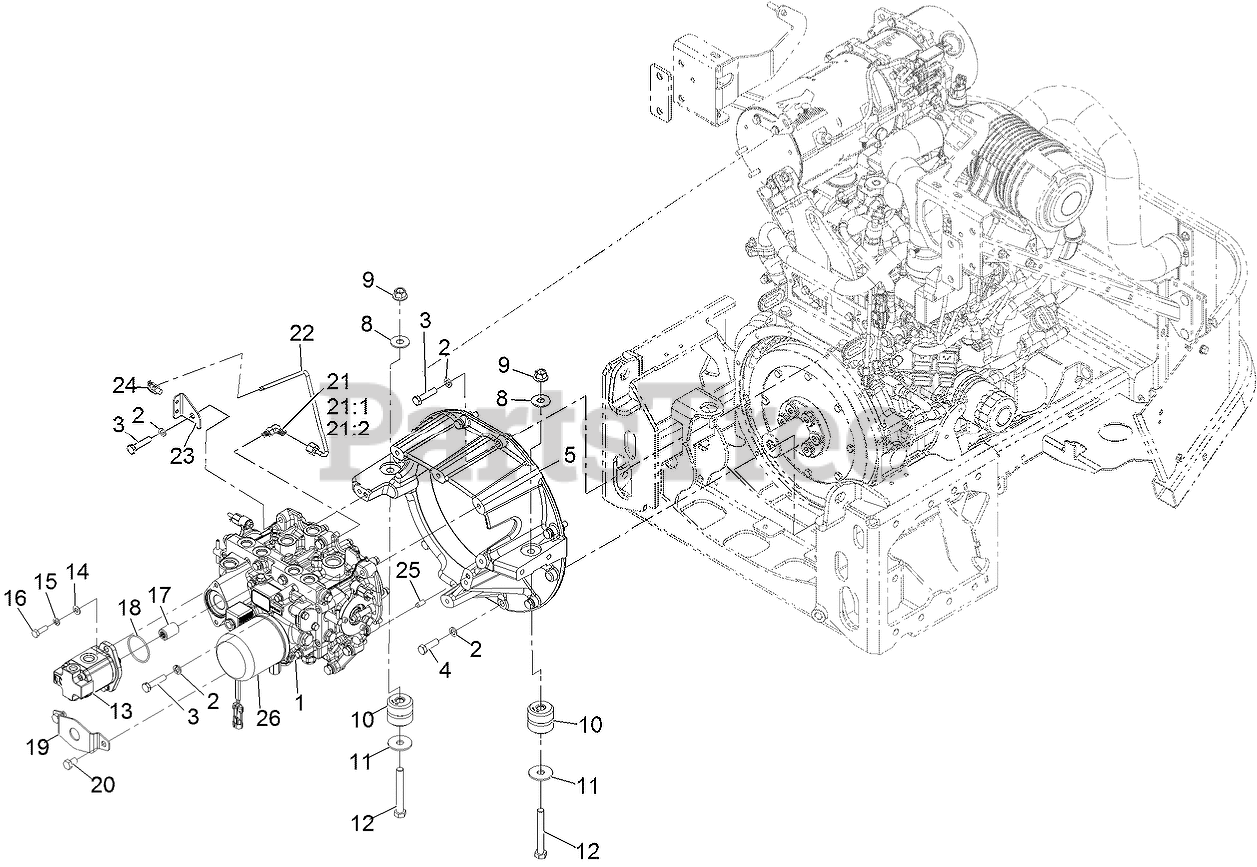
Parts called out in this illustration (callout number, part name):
1	TRANSMISSON ASM
2	WASHER-LOCK
3	SCREW-HH
4	SCREW-HH
5	HOUSING-FLYWHEEL
8	WASHER-FLAT
9	Nut-Lock 1/2-13
10	MOUNT-ISOLATOR
11	WASHER-THRUST
12	SCREW-HH
13	HYD GEAR PUMP ASM
14	WASHER-PLAIN
15	WASHER-LOCK
16	SCREW-HH
17	COUPLER-SPLINE
19	SHIELD-SEAL
20	SCREW-HH
21	FITTING-ELBOW, 90 DEG
21:1	O-RING
21:2	O-RING
22	TUBE ASM
23	SUPPORT-TUBE
24	CLIP-TIE
25	PIN-DOWEL
26	FILTER-OIL, HYD
